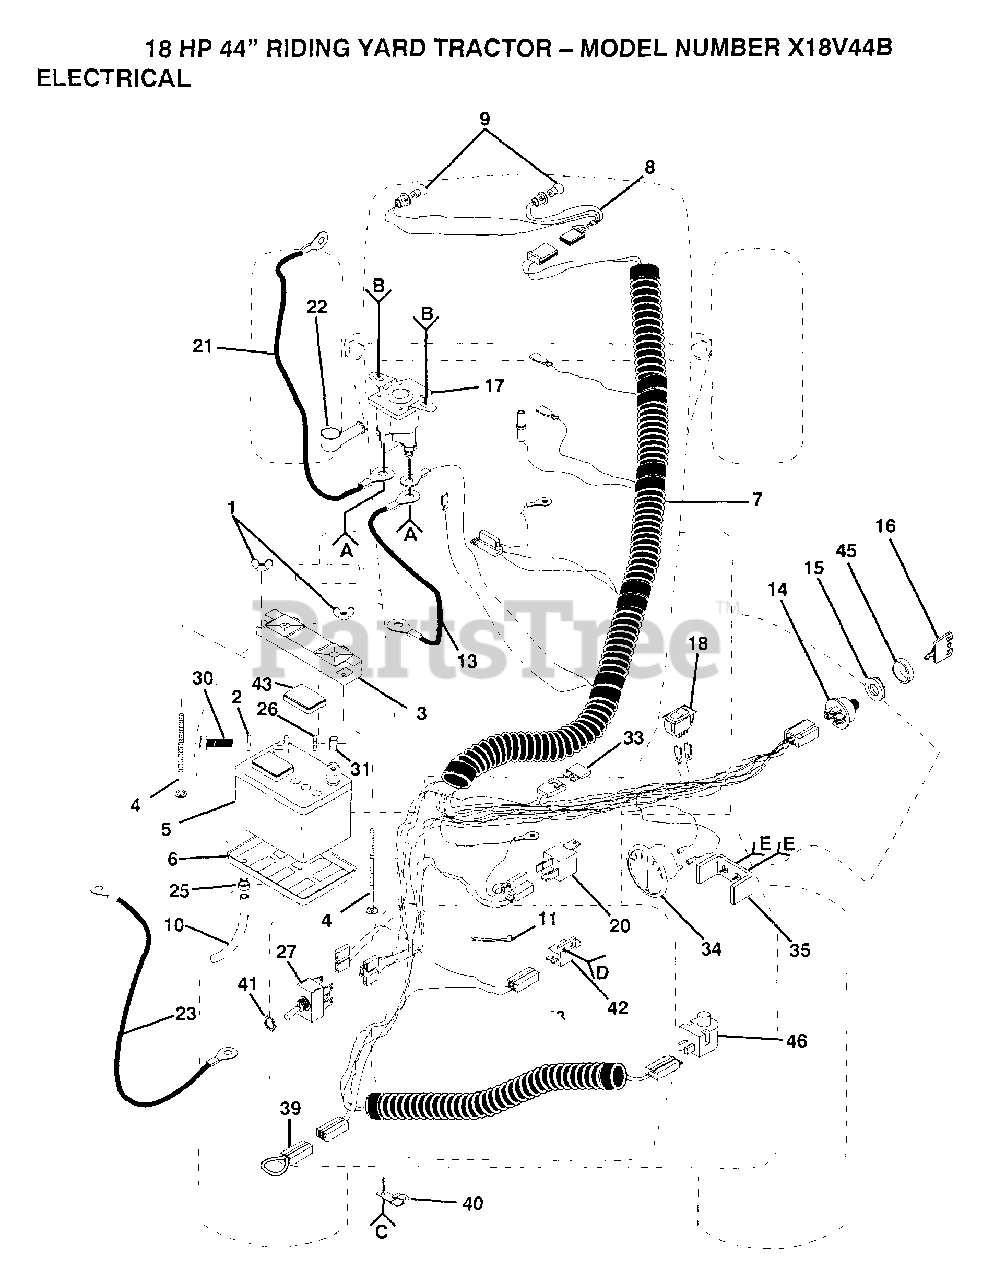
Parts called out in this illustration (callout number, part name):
2	WASHER
4	BOLT
6	"TRAY T, BATTERY"
7	HARNESS
11	WIRE TIE
13	CABLE-BATTERY T
16	KEY
18	SWITCH LT
20	RELAY ASSY T
21	"CABLE T, BATTERY"
23	CABLE T
25	HOSE CLAMP T
26	LOCKWASHER
30	BOLT LT
33	FUSE HYT
34	AMMETER T
40	CLIPT
41	HEX NUT T
42	SWITCH-INTER. GT
43	"CAP,BATTERY "
46	SWITCH SEAT
